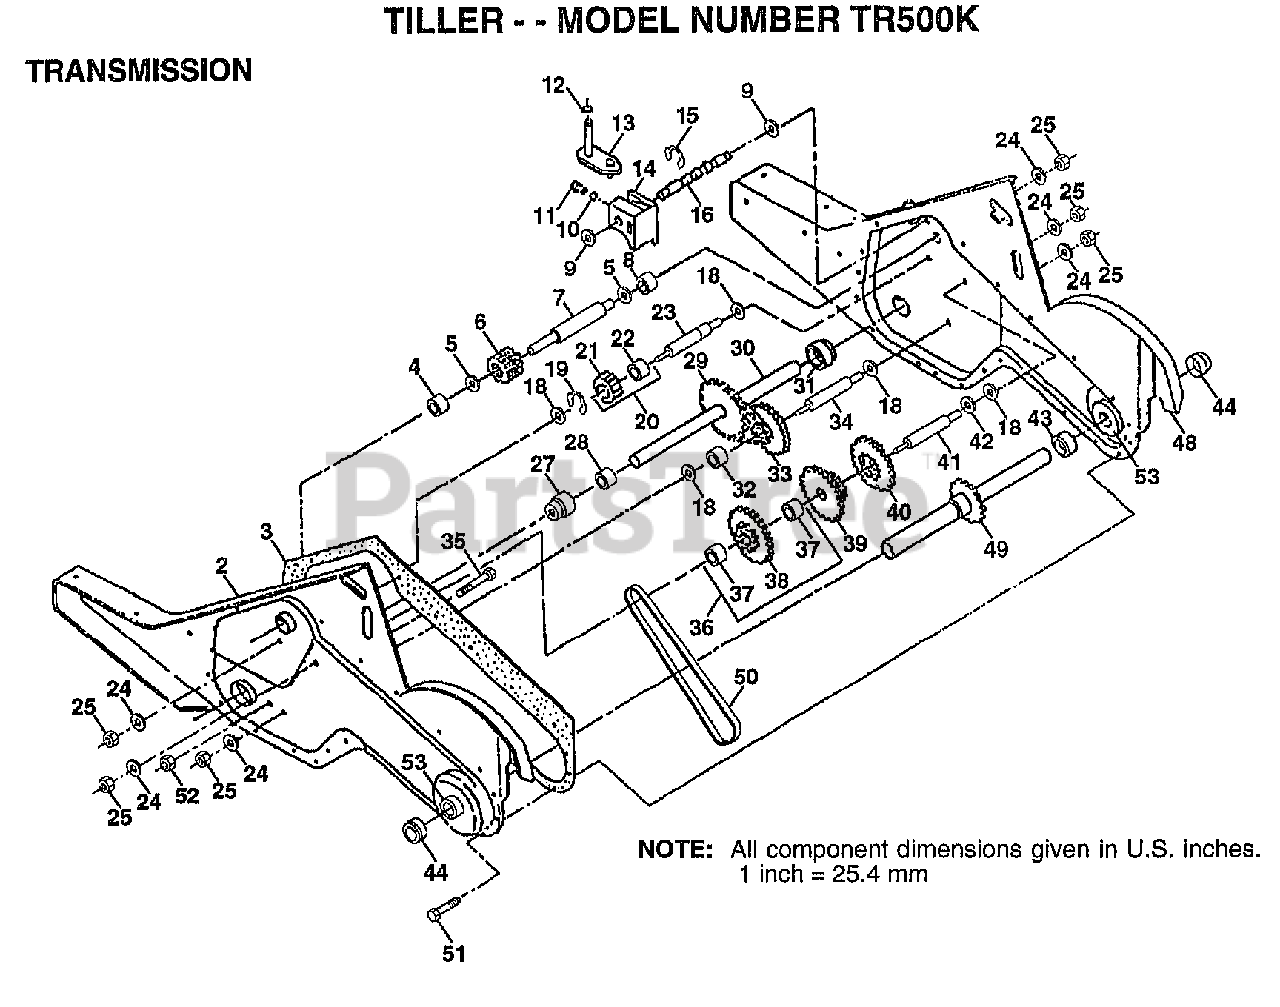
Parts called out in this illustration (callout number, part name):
2	GEARCASE LH W/BRG
3	GASKET TI
4	NEEDLE BRNG LT
5	"T, BEARING"
6	GEAR PINION INPUT
7	"SHAFT.INPUT.""D"""
8	"TI, BEARING"
9	WASHER SEAL
11	SPRING-SHIFT CRT
12	O-RING TI
13	BRACKET ASM SHIFT
14	SHIFT FORK TI
15	KLIP RING
16	SHAFT.SHIFTER
18	WASHER
19	KLIP RING
20	GEAR ASSY CRT
21	GEAR-REV IDLR CRT
22	NEEDLE BEARING TI
23	SHAFT CRT
24	LOCKWASHER
25	NUT.ASF.HEX.7/16
27	BEARING.SHAFT.LH.
28	BUSHING TI
29	CHAIN CRT
30	GROUND SHAFT ASSY
31	BEARING.SHAFT.RH.
32	SPACER TI
33	SPRCKT 8 GEAR CRT
34	SHFT 2ND RED. CRT
35	SCRW WHIZ LOK CRT
36	SPROCKET.ASM.W/BR
37	BEARING
39	GEAR TI
40	GEAR TI
41	REDUCTION SHFT TI
42	BRNG RACE
43	SPACER TI
44	SEAL ASM-OIL
48	GEARCASE RH W/BRG
49	TINE SHAFT
50	CHAIN.50 LINK TI
51	SCREW
52	NUT.HEX.5/16-18
